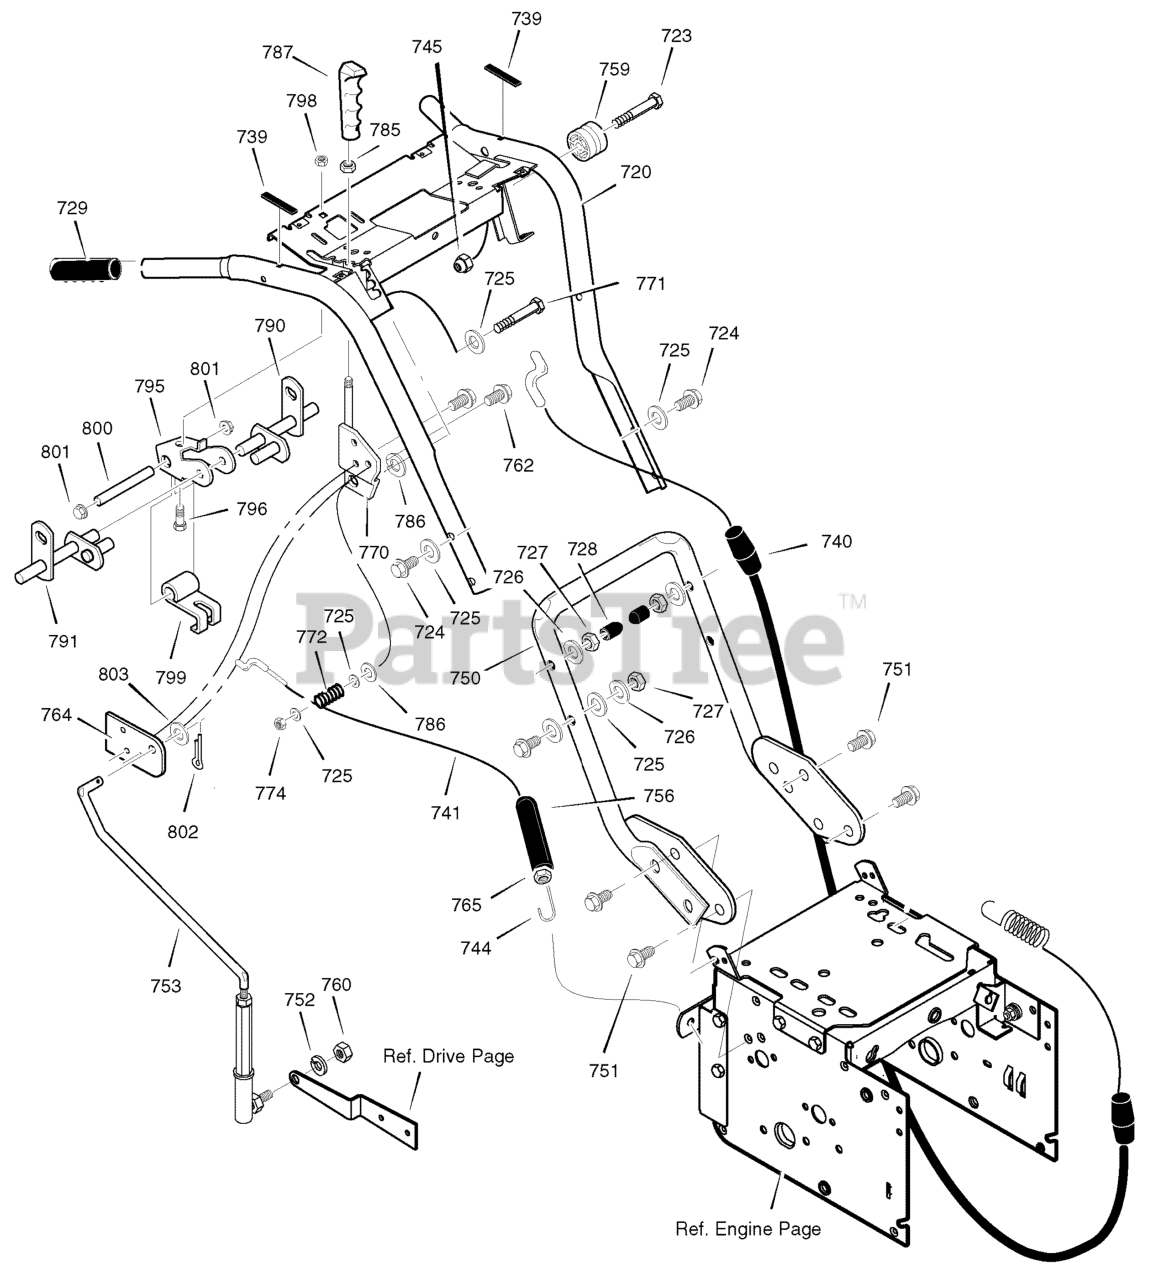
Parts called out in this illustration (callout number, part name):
720	ASSY., HANDLE
724	SCREW
725	WASHER
726	WASHER
728	STOP, PLASTIC
729	GRIP, HANDLE
739	BUMPER
740	CABLE, DRIVE
741	CABLE, AUGER
744	SPRING, AUGER CLUTCH
745	NUT, HEX 1/4-20
750	HANDLE, LOWER
751	SCREW
752	WASHER
753	ASSEMBLY, ROD
756	BOOT, SPRING
759	SPOOL, CABLE
760	NUT, 5/16-24
762	SCREW 1/4-20X0.63
764	BRACKET, CONTROL
765	NUT, 1/4-20
770	BRACKET, SHIFT
771	SCREW
772	SPRING
774	NUT, HEX, 3/8-16
785	NUT, HEX, 3/8-16
786	WASHER
787	KNOB, SHIFT
790	ROD, ASSY LH
791	ROD, ASSY RH
795	BRACKET, CAM
796	SCREW
798	NUT, NYLOCK
799	CAM LOCK
800	PIN, SPRING PIVOT
801	NUT, PUSH ON
802	PIN, COTTER
803	WASHER
